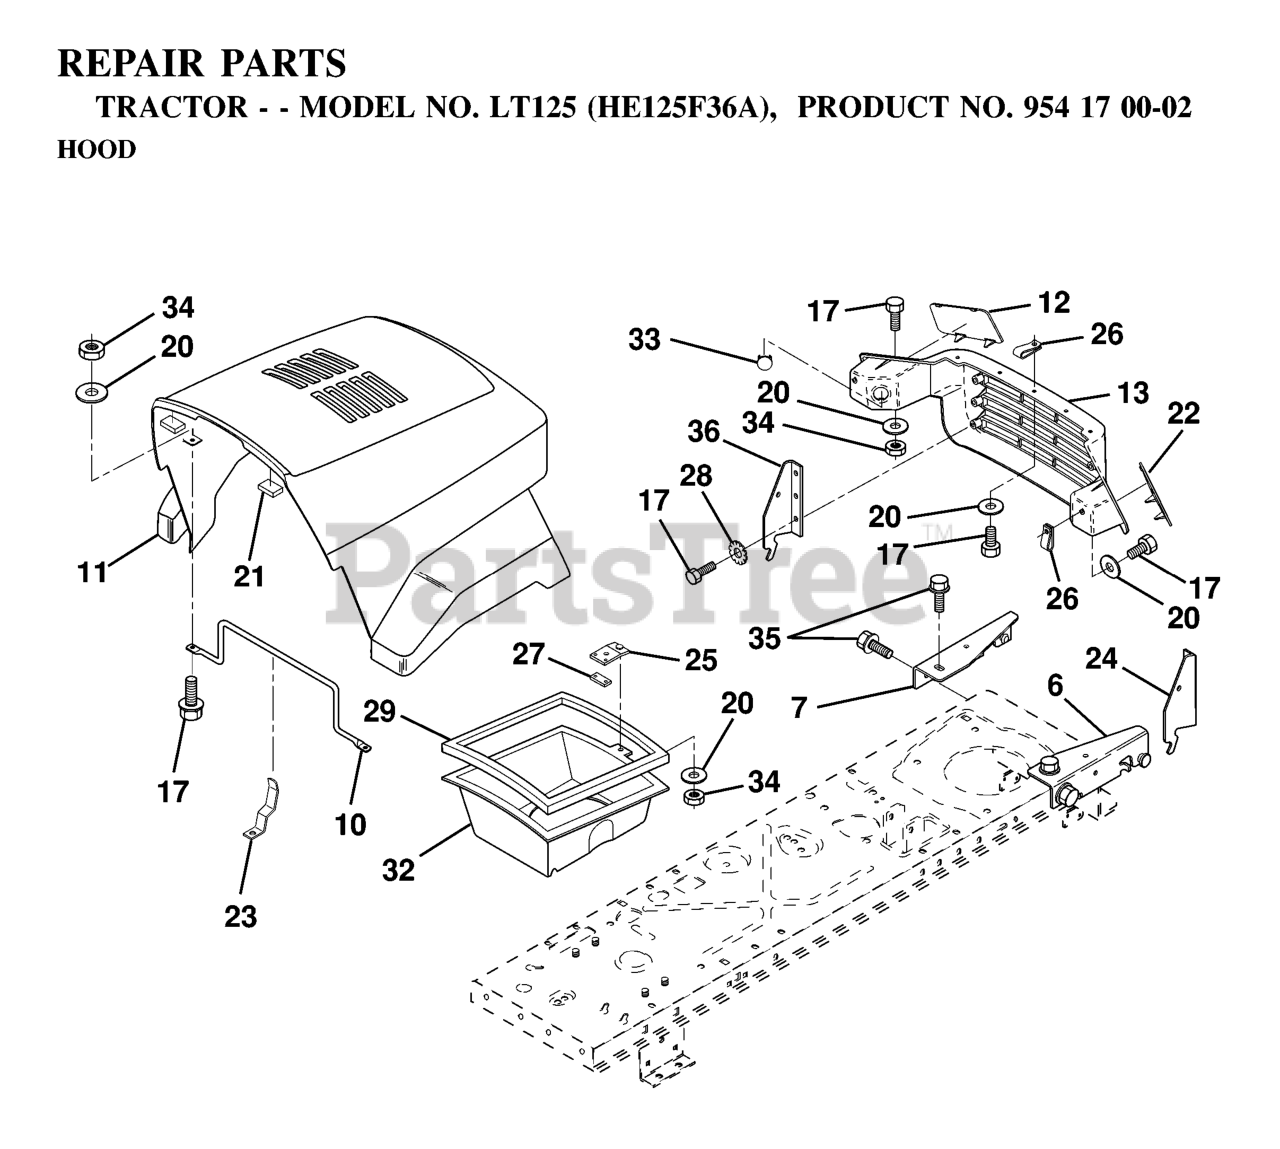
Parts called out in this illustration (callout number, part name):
6	BRACKET ASSY HOOD
7	BRACKET ASSY
10	BRACE HOOD
12	LENS.LR.LH.HUSQV.
13	GRILL
17	BOLT
21	BUMPER HOOD T
23	HOOD LATCH
24	BRACKET PIVOT
26	CLIP TINNERMAN
28	Washer, Lock, External Tooth 1/4
29	FOAM STRIP LT
33	CVR LIGHT SOCKET
34	NUT.CROWNLOCK.1/4
35	SCREW.THDROL.5/16-18X3/4.TTY
36	BRACKET HOOD
